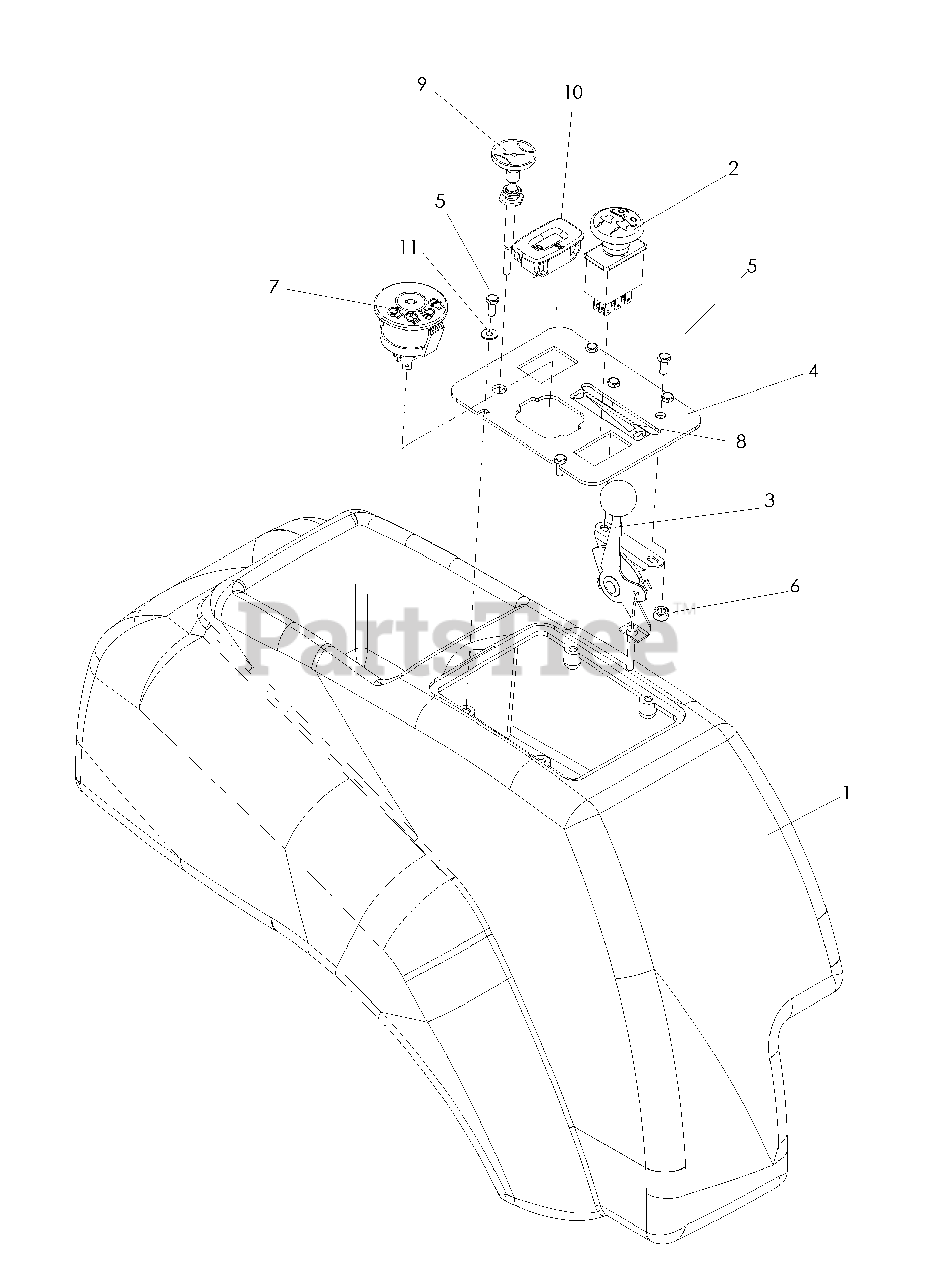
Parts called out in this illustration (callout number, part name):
2	CLUTCH SWITCH
3	THROTTLE CABLE
4	CONSOLE PLATE
5	HCS #10-24 x 1/2
6	NUT #10-24 NYLOC
7	IGNITION SWITCH
8	DECAL, THROTTLE
9	CHOKE CONTROL
10	HOUR METER
11	WASHER #10
